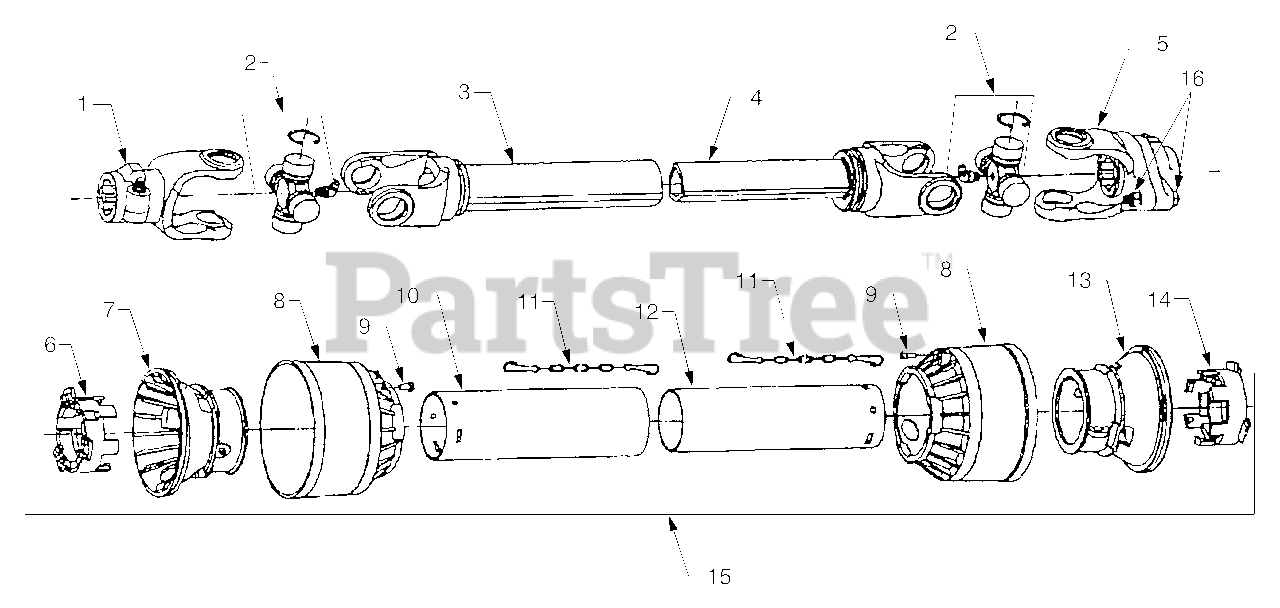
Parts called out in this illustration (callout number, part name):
1	Yoke 1 3/8 6
2	Cross, Bearing
3	Outer Tube & Yoke
4	Inner Tube & Yoke
5	Yoke, Shearbolt
6	Outer Locking Ring
7	Outer Tube Rigid Cone
9	Pin For Stop Rotation
10	Outer Shield
12	Inner Shield
13	Inner Tube Rigid Cone
14	Tube Bearing Inner
15	Shield Complete
16	Shear Bolt & Nut
